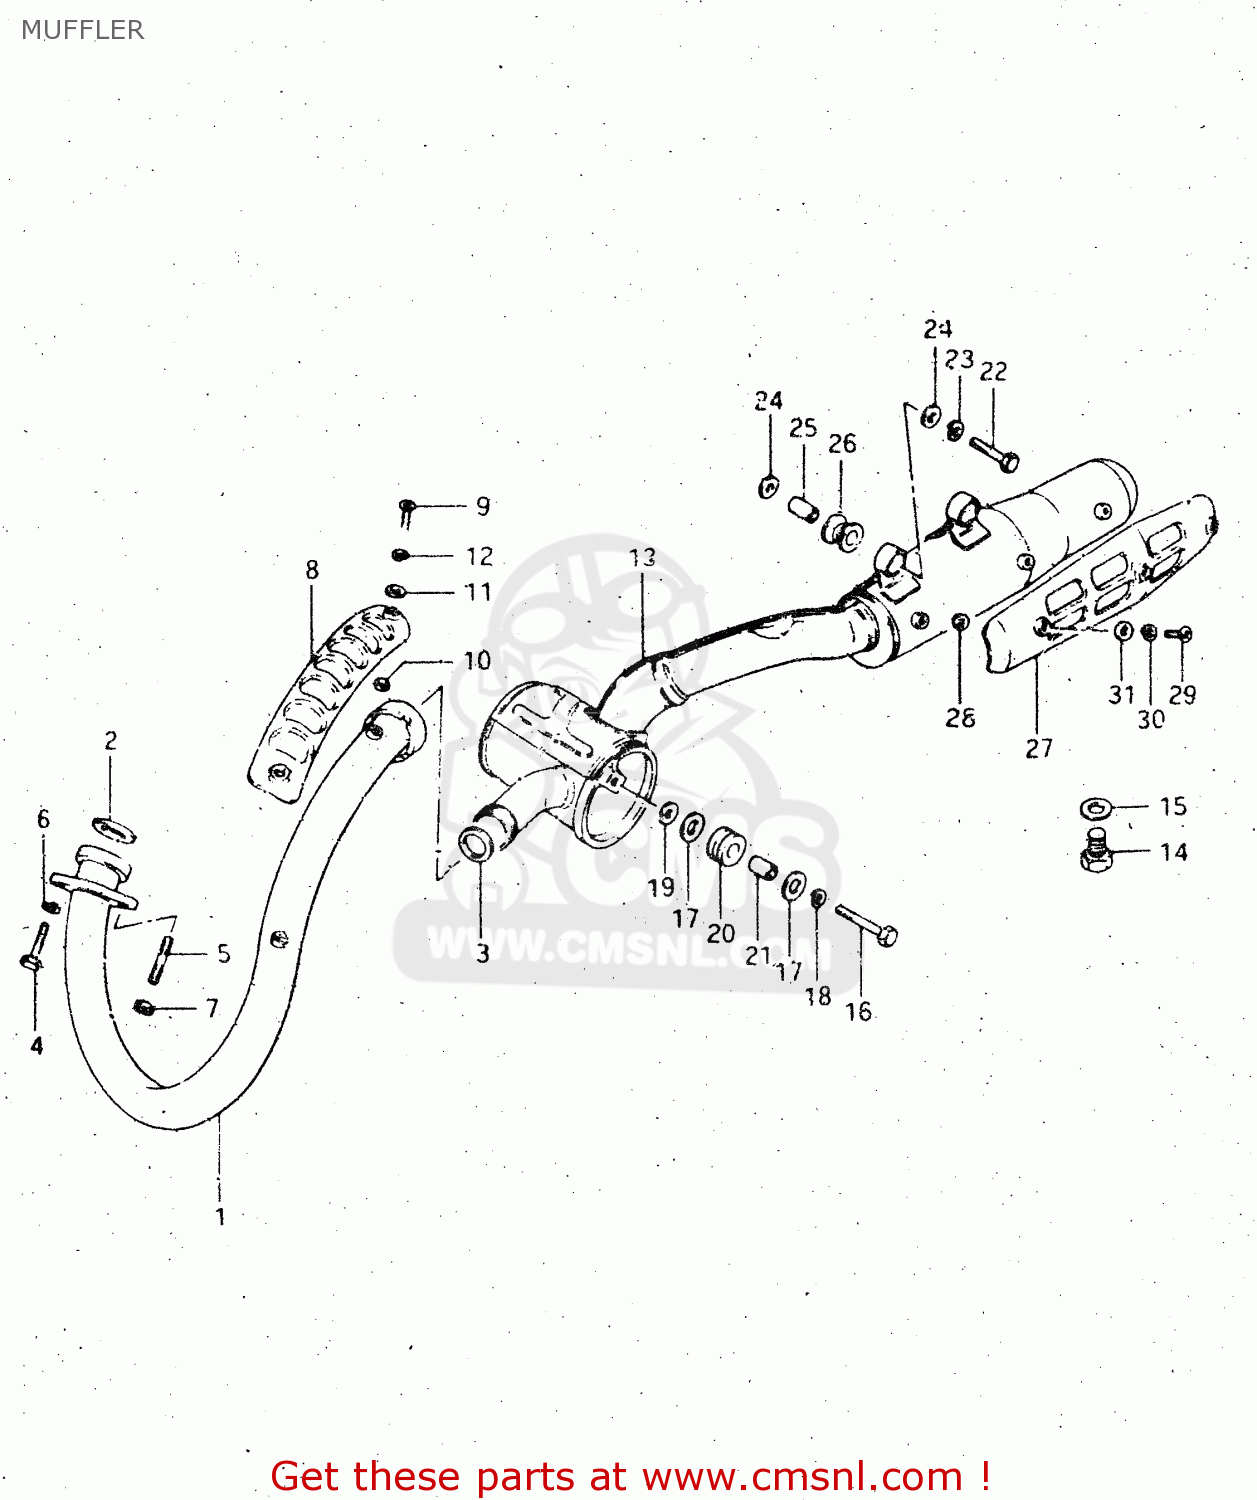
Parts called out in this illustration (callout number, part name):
1	PIPE,EXHAUST
2	GASKET,EXHAUST PIPE (NAS)
3	GASKET,EXHAUST PIPE (NAS)
4	BOLT
5	STUD BOLT
6	LOCK WASHER
7	NUT
8	COVER,EXHAUST PIPE
9	SCREW
10	GASKET 6.2X12X1.5 (MCA)
11	WASHER
12	LOCK WASHER
13	MUFFLER ASSY
14	PLUG(12X9)
15	GASKET(12X16X2) (NAS)
16	BOLT
17	WASHER (8.5X20X1.6)
18	LOCK WASHER
19	GASKET
20	CUSHION
21	SPACER (8.6X13.8X13)
22	BOLT 8X40
23	LOCK WASHER
24	WASHER (8.5X20X1.6)
25	SPACER (8.6X12X17.5)
26	CUSHION
27	COVER,SECOND MUFFLER
28	GASKET 6.2X12X1.5 (MCA)
29	SCREW
30	LOCK WASHER
31	WASHER
